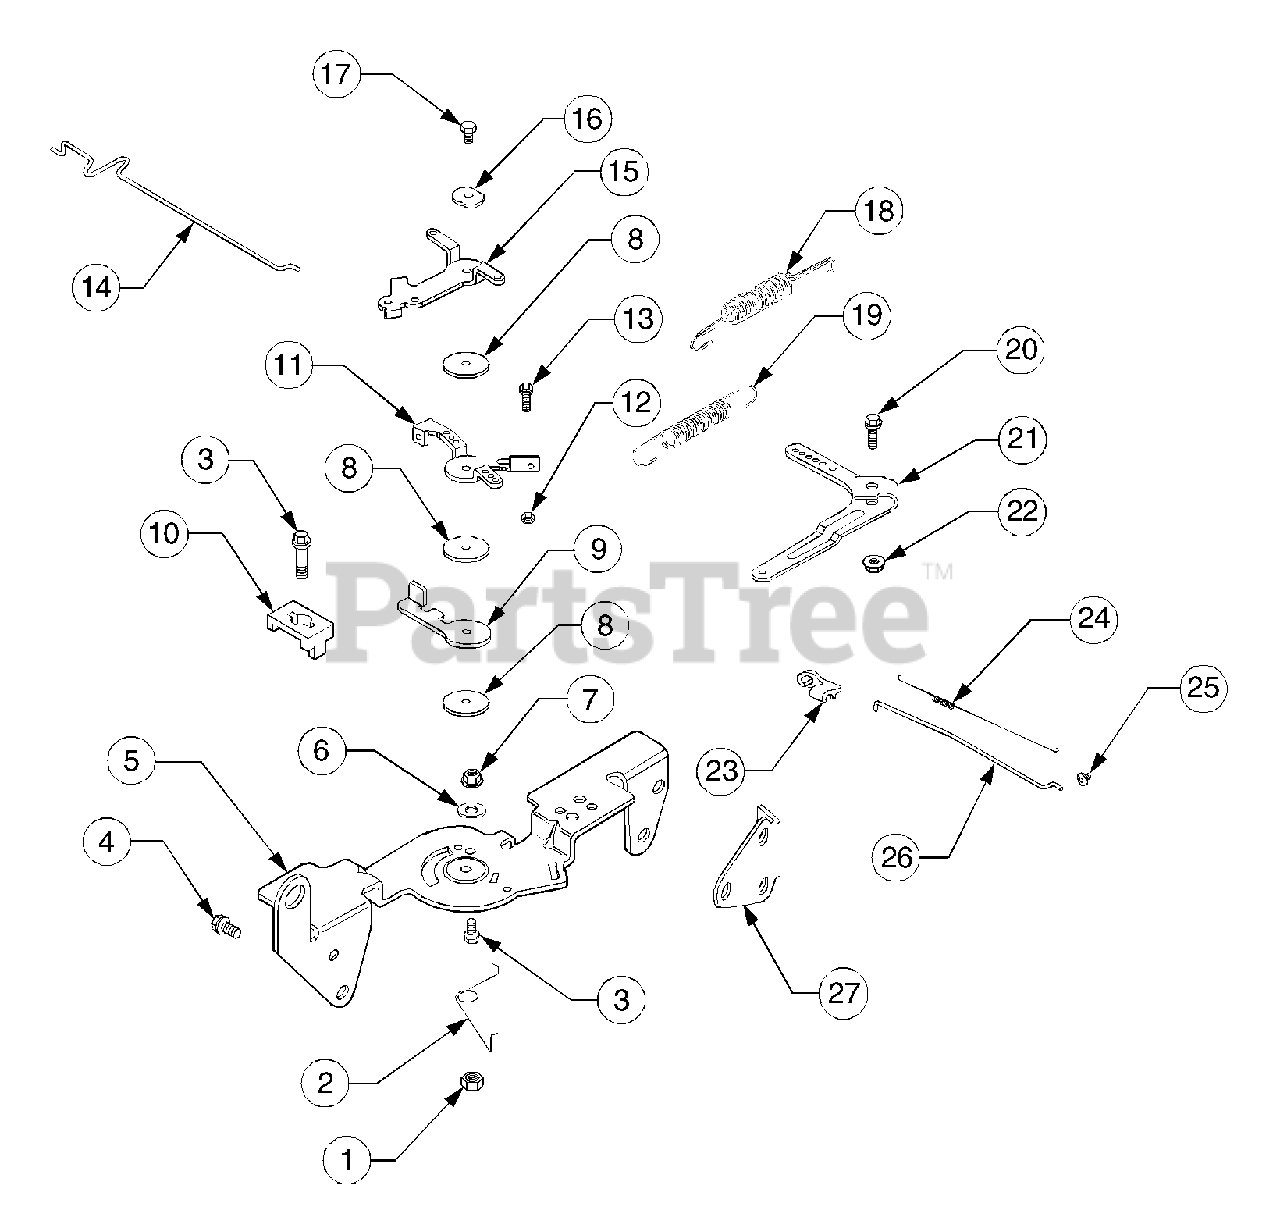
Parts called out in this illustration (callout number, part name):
1	Nut, Hex Lock M5 x 0.8
2	Spring, Choke Return
3	Screw, Hex Flange M5 x 0.8 x 16
4	Screw, Hex Flange M6 x 1.0 x 16
5	Bracket, Control
6	Washer, Lock
7	Nut, Hex Flange
8	Washer, Plain 5.5mm
9	Lever, Throttle Actuator
10	Clamp, Cable
11	Lever, Throttle Control
12	Nut, Hex M4 x 0.7
13	Screw, Hex Cap M4 x 0.7 x 30
14	Linkage, Choke
15	Lever, Choke
16	Washer, Spring 1/4"
17	Screw, Hex Flange M5 x 0,.8 x 20
18	Spring, Throttle Limiter
19	Spring, Governor
20	Screw, Round Hd. Square Neck
21	Lever, Governor
22	Nut, Hex Flange M6 x 1.0
23	Bushing, Linkage Retaining
24	Spring, Linkage
25	Bushing, Linkage Retaining
26	Linkage, Throttle
27	Bracket, Support
